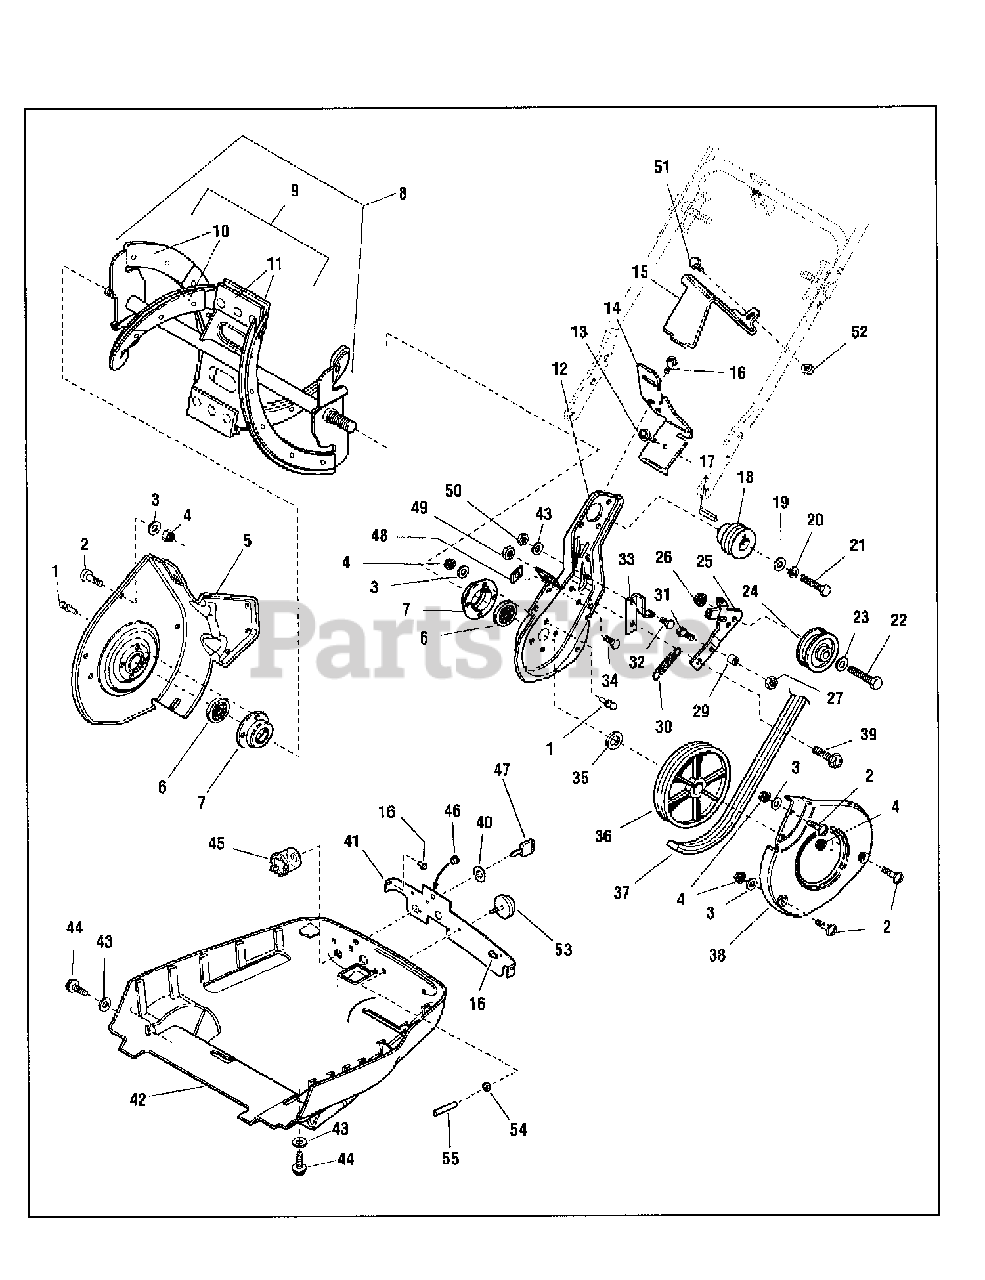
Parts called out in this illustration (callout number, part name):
1	RIVET, Pop, 1/4 x 1/2"
2	SCREW, Truss Head Torx, #10-24 x 5/8" GR 5
3	WASHER, Rivet
4	NUT, Hex Lock, #10-24
5	FRAME, Right Side
6	BALL BEARING, Auger
7	RETAINER, Bearing
8	WELDMENT, Auger
9	KIT, Flighting Replacement
10	FLIGHTING, Rubber
11	CENTER FLIGHT, Rubber
12	FRAME, Left Side
13	SCREW, Hex Washer Slotted Head Plastite #10-14 x 5/8"
14	SHIELD, Belt
15	AIR DEFLECTOR
16	SCREW, Hex Head, #10-24 x 1-1/4"
17	KEY, Parallel .187 x .187 x 1"
18	PULLEY, Drive
19	WASHER
20	LOCKWASHER, 5/16" Spring
21	CAPSCREW, Hex Head, 5/16-24 x 1-1/4", GR 5
22	CAPSCREW, Hex Head, 3/8-16 x 1-1/2", GR 5
23	WASHER, 3/8"
24	PULLEY, Idler
25	IDLER ARM
26	NUT, Flange Whiz Lock, 3/8-16
27	NUT, Hex Centerlock 1/4-20
29	ROLLER, Belt Stop
30	SPRING, Idler Return
31	CAPSCREW, Hex Head, 1/4-20 x 1" GR 5
32	CAPSCREW, Hex Head, 1/4-20 x 7/8" GR 5
33	BRACKET, Belt
34	SCAPCREW, Hex Washer Head Taptite, 1/4-20 x 5/8"
35	SPACER, Pulley
36	PULLEY, Driven
37	BELT, Drive
38	BELT GUARD
39	IDLER PIVOT BOLT
40	FLANGE NUT, Ignition Switch, 5/8-32
41	CONTROL PANEL
42	HOUSING, Lower
43	WASHER, 1/4
44	SCREW, Hex Head, Taptite, 1/4-20 x 7/8"
45	SWITCH, Ignition
46	SNAP BUSHING, 1/4"
47	KEY, Ignition
48	SPEED NUT, 1/4-20
49	NUT, Hex Lock ESNA Light, 5/16-18
50	NUT, Hex Lock Esna 1/4-20
51	SCREW, Hex Head, Taptite, #10-20 x 1/2"
52	NUT, Hex Lock, #10-24
53	PRIMER, Tecumseh 1/4-20
54	NUT, 1/4-20 Hex, GR 5 or B
55	LINE, Primer
